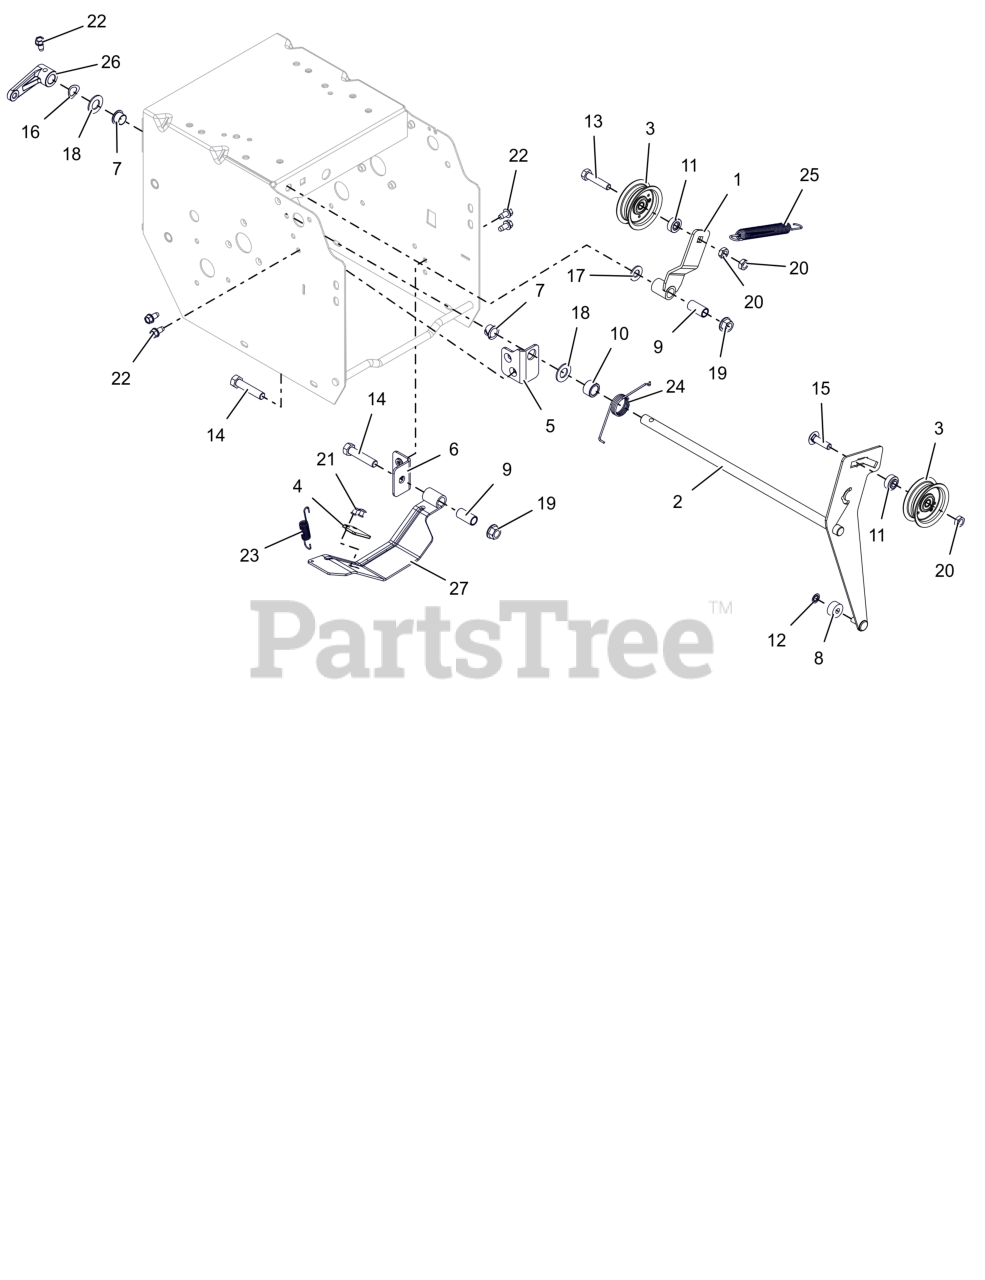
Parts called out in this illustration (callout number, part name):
1	WELDMENT, TRACTION IDLER ARM
2	WELDMENT- ATTACHMENT IDLER ARM
3	IDLER, FLAT - 2.00"
4	PAD, BRAKE
5	BRACKET, MOUNT - IDLER ARM
6	BRACKET, MOUNT - BRAKE
7	BUSHING, POLYLINER-.50 SPLIT
8	BSHG,SLV .265 X .625 X .375
9	BSHG-SLV .385X.500X1.045
10	BSHG-SLV .510X.751X.475
11	SPCR, BRG .315X.500X.358X.281
12	RG-RTNG-EXT .250X.010
13	BLT, HEX .31-18X1.50 G5 ZCC
14	BLT, HEX .38-16X1.75 G5 ZCC
15	BLT, RHSSN .31-18X1.125 G5 ZCC
16	WSHR-WAVE .50X.75X.015 .13FRHT
17	WSHR,FLT .406X.812X.065 ZCC
18	WSHR, FLT .531X1.00X.063 ZCC
19	NUT-LK-TOP-FLG .38-16 ZC120
20	NUT-LK-CTR-JAM .312-18 GB ZCC
21	RVT, POP .1875 ZCC
22	SCR-TAP .25-20X.50 HWH ZCC
23	SPRING-EXT .437 X .438 X 2.64
24	SG-TORS .075 X .955
25	SPRING, SWIVEL HOOK EXTENSION
26	ARM CLUTCH - ATTACHMENT
27	BRAKE ARM W/PAD
